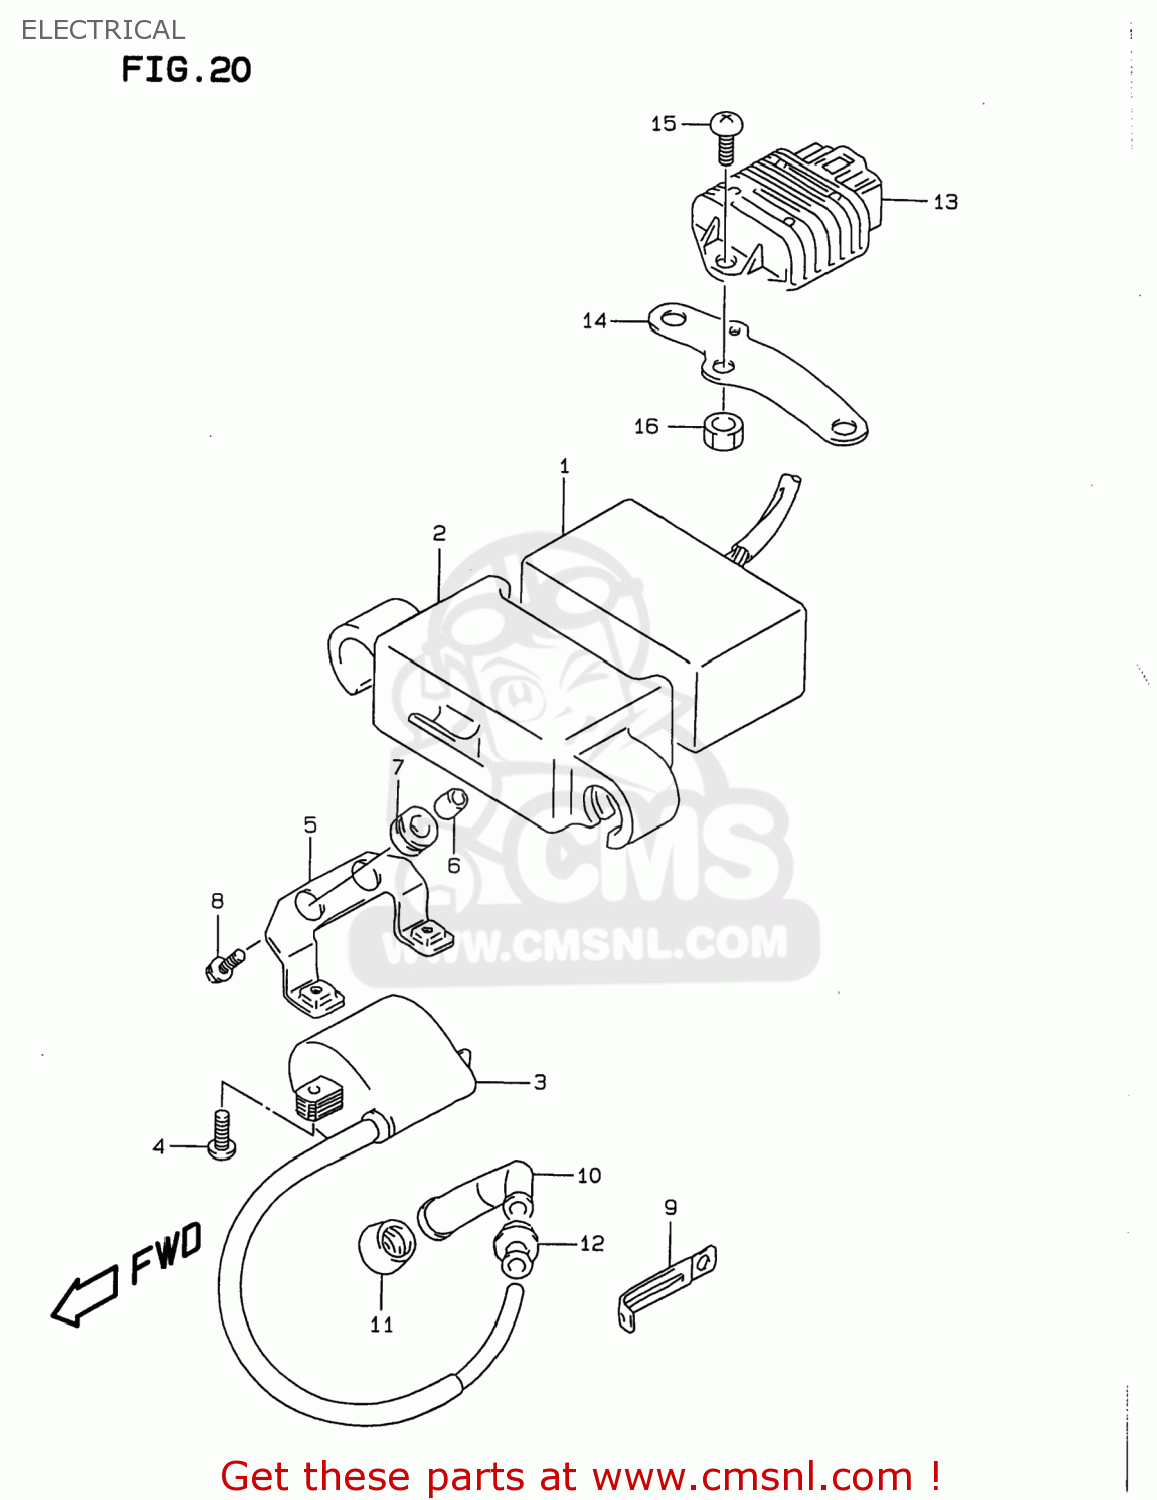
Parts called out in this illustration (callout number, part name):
1	CDI UNIT
2	CUSHION,CDI UNIT
3	COIL ASSY,IGNITION
4	SCREW, 6X20
5	BRACKET,IGNITION COIL
6	SPACER(6.5X9X6.7)
7	CUSHION
8	BOLT
9	CLAMP(L:45)
10	CAP,SPARK PLUG
11	SEAL,SPARK PLUG
12	SEAL,HIGH TENSION CORD
13	REGULATOR ASSY
14	BRACKET,REGULATOR
15	SCREW 6X12
16	NUT 6MM
